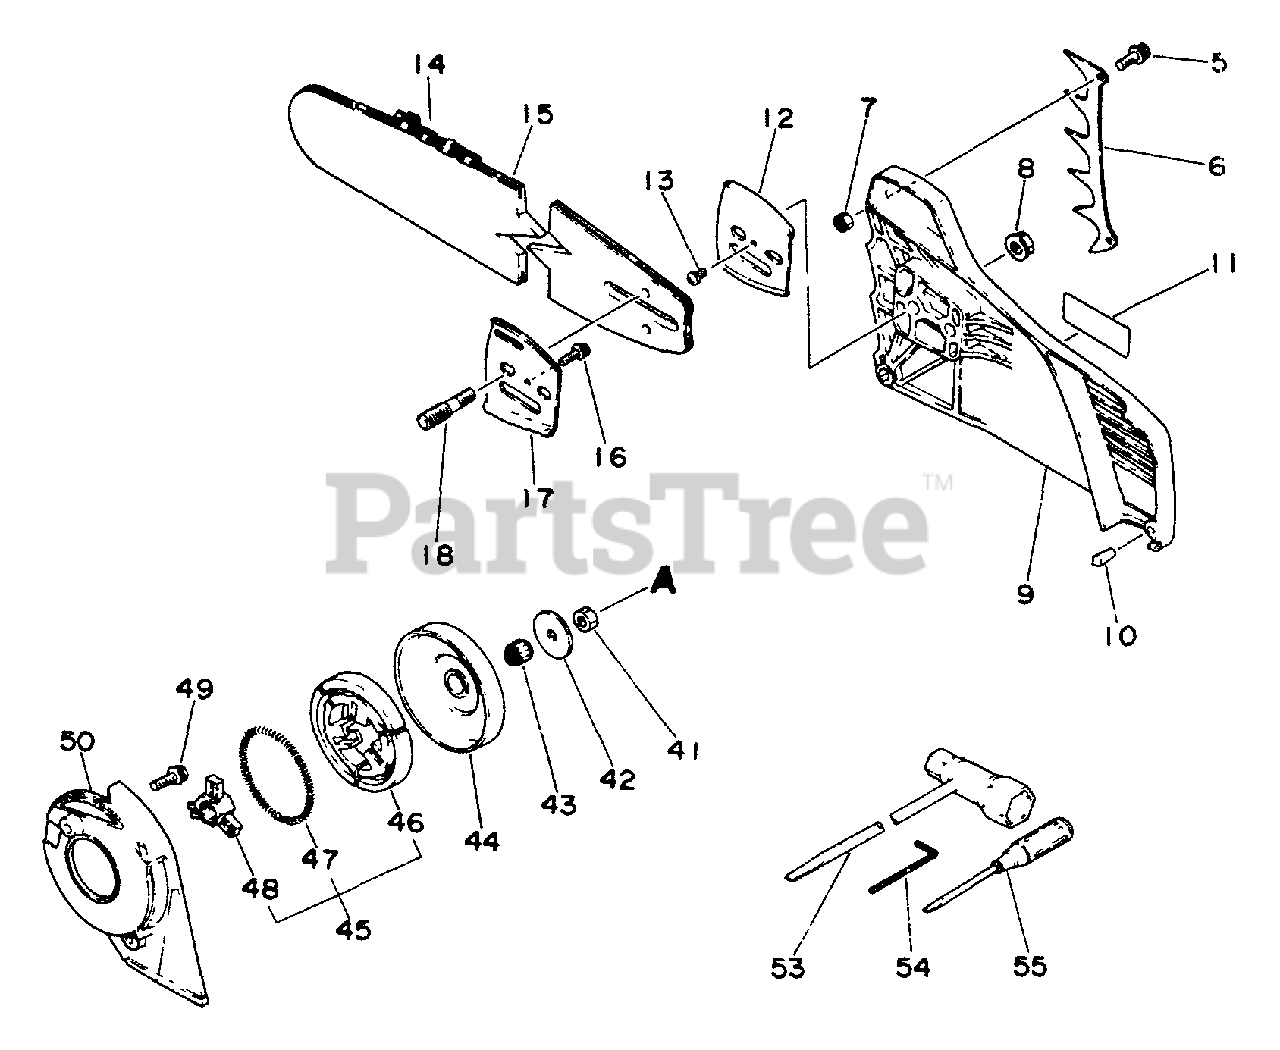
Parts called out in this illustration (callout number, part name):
5	BOLT 5×12
6	SPIKE, BUMPER
7	LOCKNUT - 5
8	NUT, FLANGE M8×1.25
9	GUARD, SPROCKET
10	PIN, DOWEL
11	LABEL - ECHO
12	PLATE, SIDE
13	SCREW 3×6
14	CHAIN
15	GUIDE BAR
16	SCREW 4×12
17	PLATE, SIDE
18	STUD, GUIDE BAR
41	LOCKNUT
42	WASHER, CLUTCH
43	BEARING, NEEDLE
44	DRUM, CLUTCH
45	CLUTCH ASSY
46	SHOE, CLUTCH
47	SPRING, CLUTCH
48	HUB, CLUTCH
49	SCREW 5×16
53	T-WRENCH 13×19×180
54	WRENCH, ALLEN 4 MM
55	SCREWDRIVER, PHILLIPS
